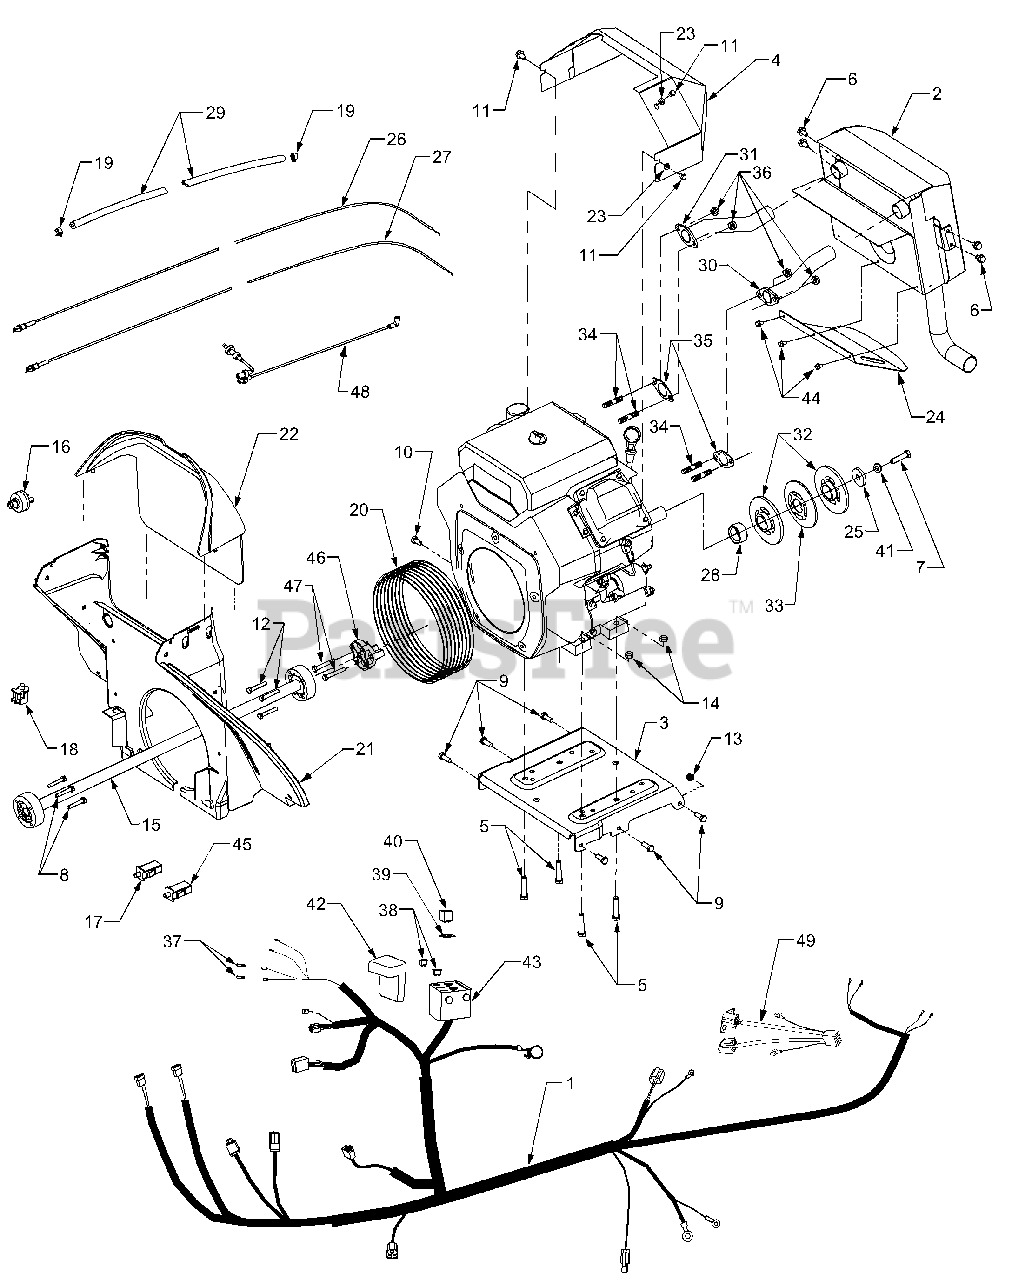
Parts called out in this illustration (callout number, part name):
1	Harness, Wire
1	Tie, Pushmount
1	Clip, Cable
2	Muffler Assembly
3	Plate, Engine Mounting
4	Shield, Muffler Heat
5	Screw, Hex Cap, 3/8-24 x 1.75 GR5
6	Screw, Hex Wash. Hd. Tapp 5/16-18 x .5
7	Screw, Hex Cap, 7/16-20 x 1.5 GR5
8	Screw, Hex Cap Lock 1/4-20 x 1.25 GR5
9	Screw, Hex Cap, 5/16-18 x .875 GR5
10	Screw, Hex Cap, M8 - 1.25 x 16MM GR5
11	Screw, Hex Cap, M6 - 1.0 x 10MM
12	Screw, Hex Cap, Lock 1/4-20 x 1.62 GR5
13	Nut, Hex Insert Lock, 5/16-18
14	Nut, Hex Lock, 3/8-24
15	Shaft, Drive, 27.125 Long
15	Drive Barrels Kit
16	Switch, Key, w/Groung
17	Switch, Plunger
18	Switch, Snap Mount
19	Clamp, Hose
20	Boot, Intake
21	Baffle, Lower Air
22	Baffle, Upper Air
23	Washer, Flat, .281 x .50 x .06
24	Shield, Lower Exhaust
25	Washer, Flat, .417 x 1.5 x .225
26	Cable, Throttle Control
27	Cable, Choke Control
28	Spacer, Crankshaft
29	Hose, Fuel Line
30	Pipe, Exhaust RH
31	Pipe, Exhaust LH
32	Pulley Half
33	Pulley, Center
34	Stud, M8 - 1.25 x 33MM
35	Gasket, Exhaust
36	Nut, Hex, M8 x 1.25
37	Bulb, Indicator
38	Fuse, 25 Amp
39	Gasket, Silicone
40	Relay
41	Washer, Lock, 7/16
42	Cover, Fuse Box
43	Box, Fuse
44	Screw, Hex Wash. Hd. Tapp, #12-24 x .38
45	Switch, Plunger
46	Adapter, Drive Shaft
47	Screw, Hex Flange, M10 x 1.5 x 90
48	Hose, Vacuum
49	Harness Assembly, Bypass
